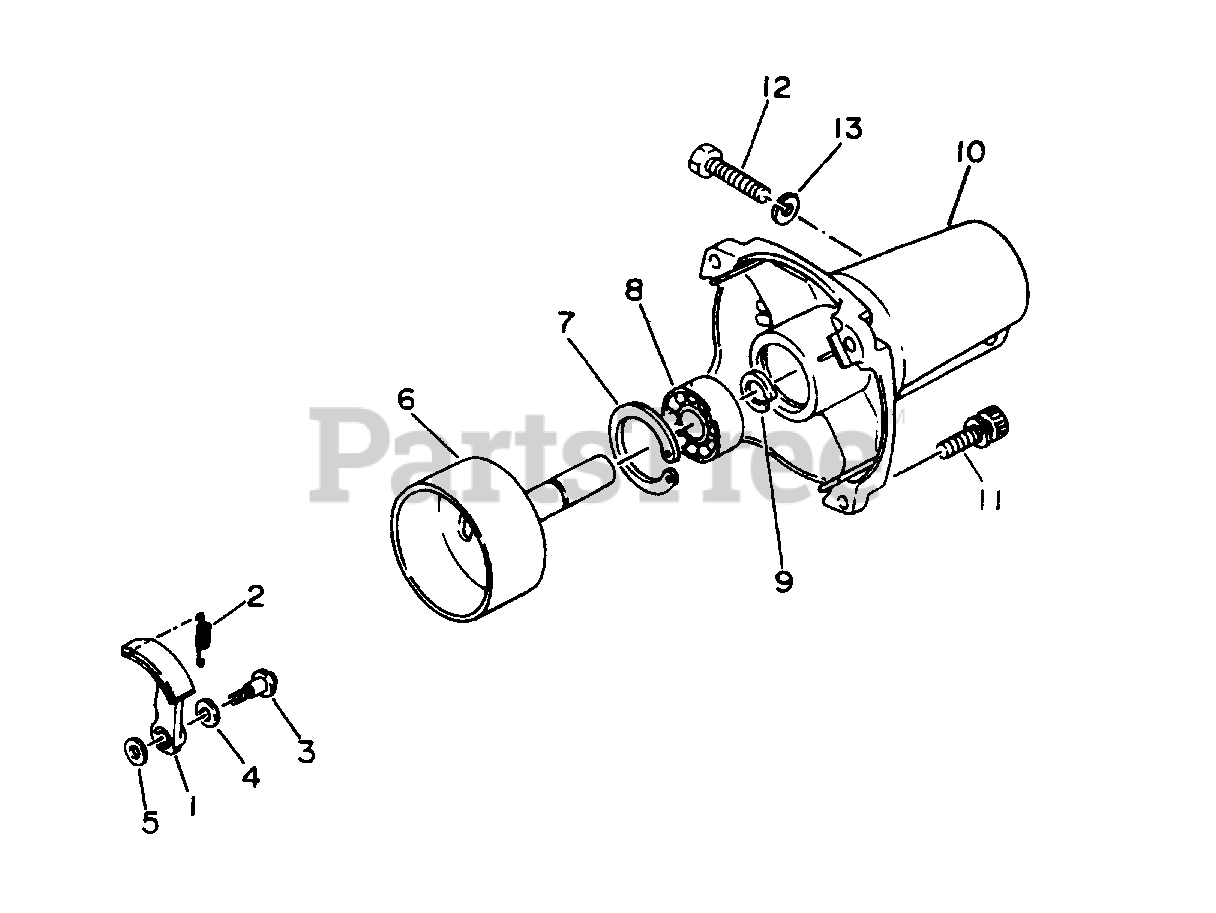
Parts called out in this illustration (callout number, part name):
7	Ring, Inner Retainer
8	Ball Bearing
9	Ring, Outer Retaining
10	Housing
11	Bolt, Socket Head
13	Washer, Spring
